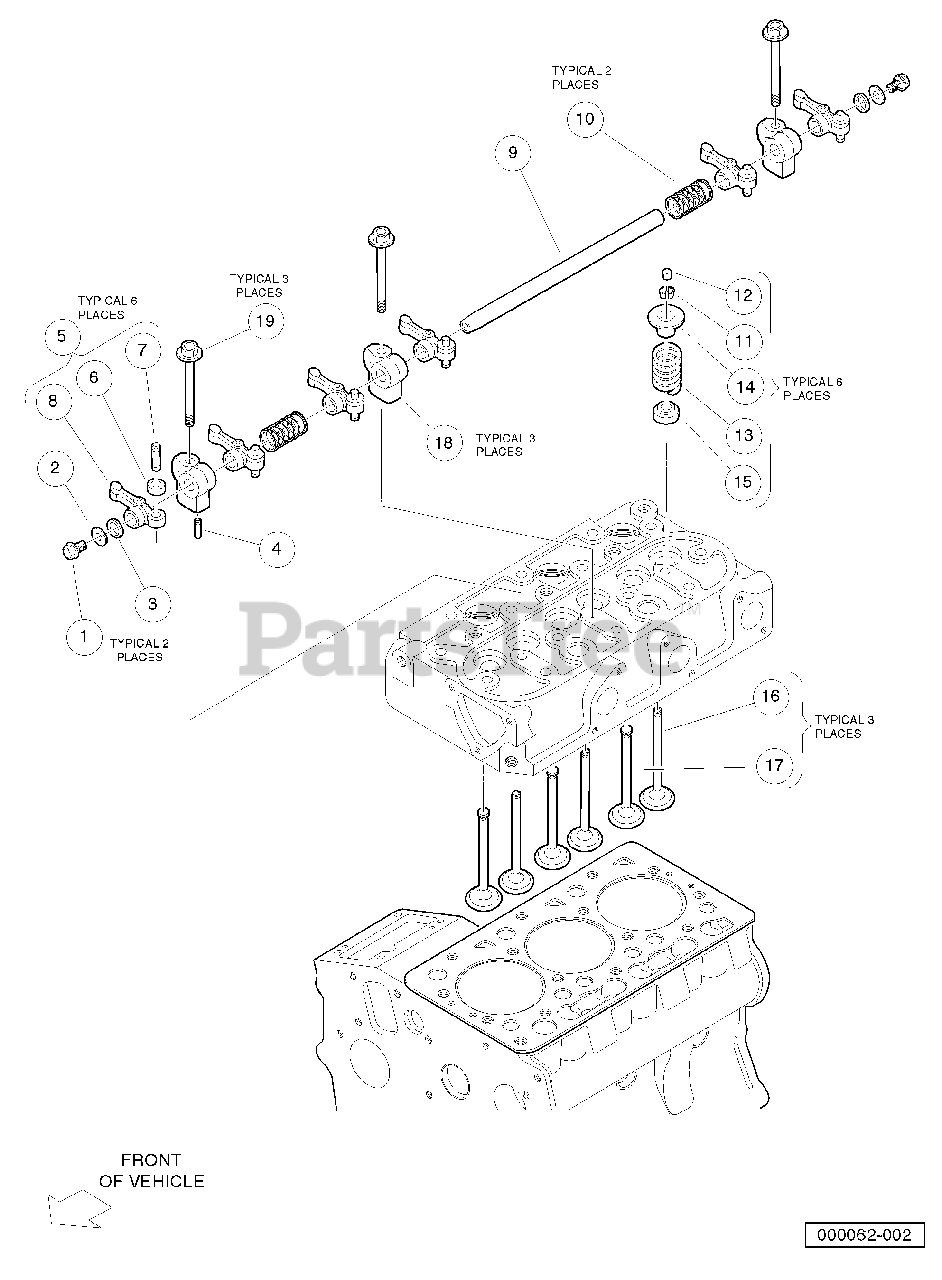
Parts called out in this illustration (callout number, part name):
1	Bolt, M6 X 1 X 8
2	Washer, D722, Plain, Rocker
3	Washer, Rocker Arm
4	Pin, Spring, D722, Rocker
5	Assy Rocker Arm
7	Screw-Adjusting
8	Arm, Rocker
9	Shaft, Rocker Arm
10	Spring, Rocker Arm
11	Collet, Valve Spring, Set
12	Cap, Valve, D722
13	Spring, Valve
14	Retainer, Spring
15	Seal, Valve Stem
16	Valve, Exhaust
17	Valve, Inlet
18	Bracket, Rocker Arm, D722 Closed-Breather
19	Bolt, Rocker Arm
